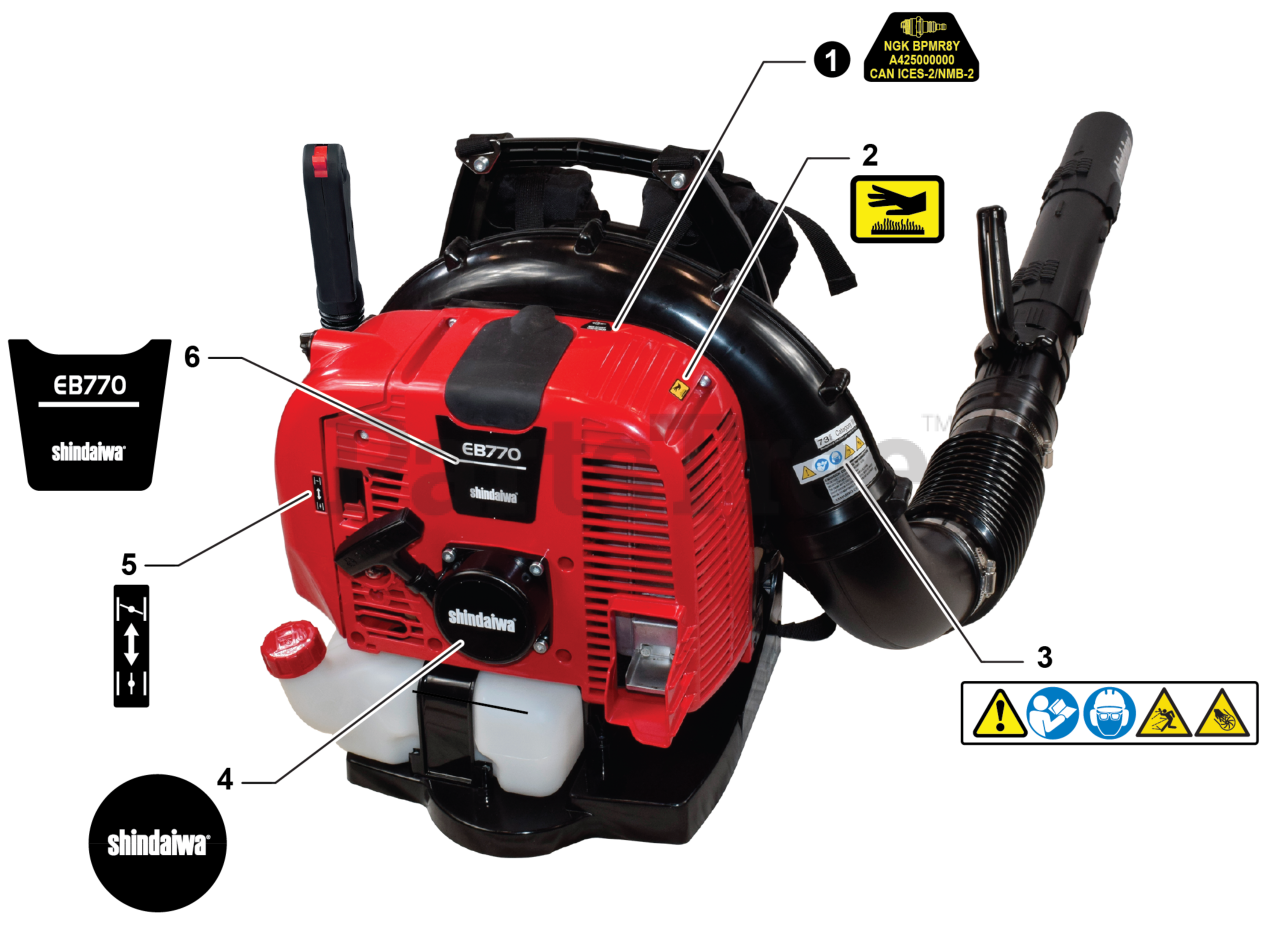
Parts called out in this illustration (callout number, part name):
1	LABEL - SPARK PLUG - BPMR8Y
2	LABEL - CAUTION - HOT
3	LABEL - CAUTION - ISO
4	LABEL - RECOIL STARTER - SHINDAIWA
5	LABEL - CHOKE
6	LABEL - EB770
